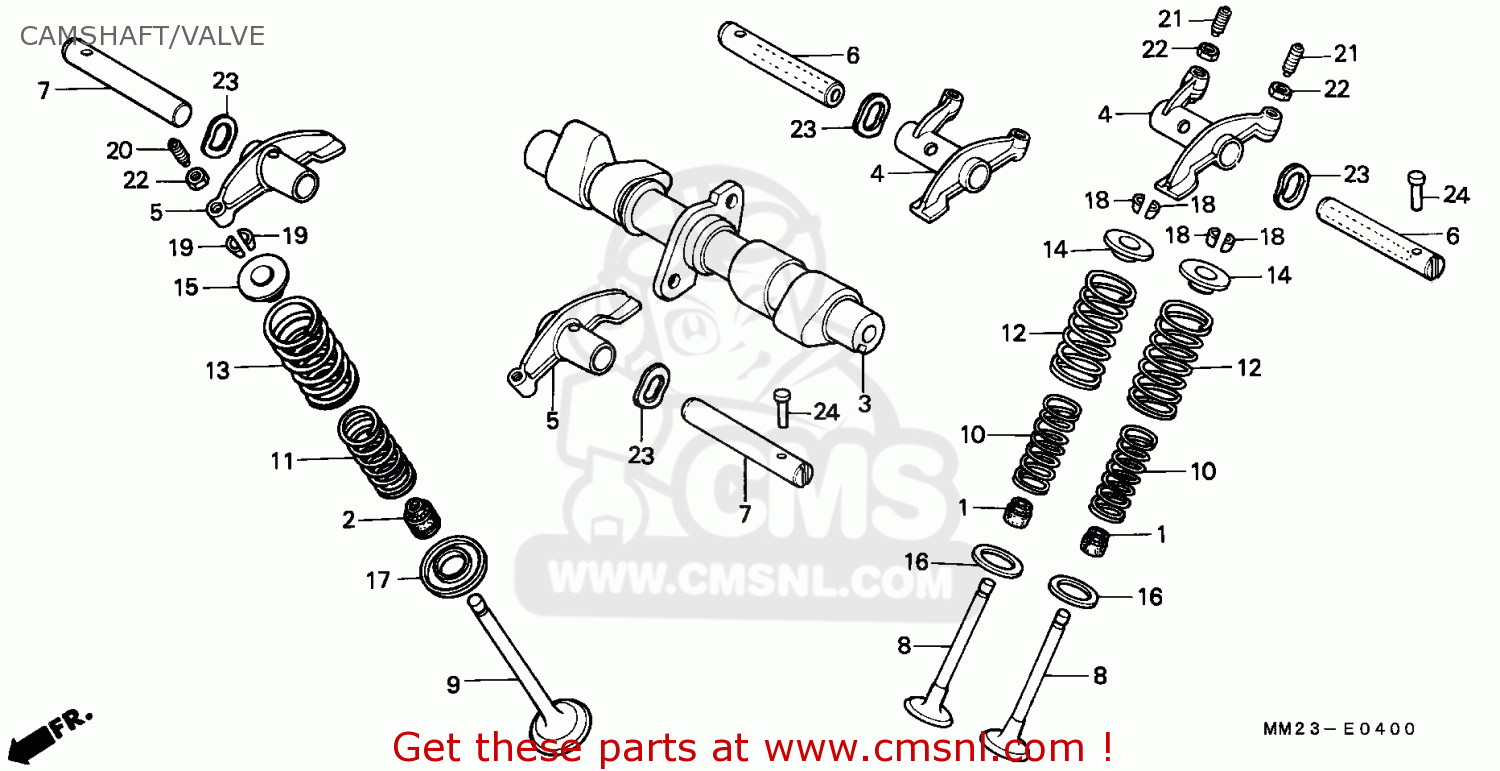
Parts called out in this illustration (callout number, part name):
1	SEAL VALVE,STEM
2	SEAL,VALVE,STEM
3	CAMSHAFT
4	ARM IN ROCKER
5	ARM EX ROCKER
6	SHAFT,IN ROCKER A
7	SHAFT,EX ROCKER A
8	VALVE,IN.
9	VALVE,EXHAUST
10	SPRING,IN.VALVE I
11	SPRING,EX.VALVE I
12	SPG,IN VALVE OUT.
13	SPRING,EX.VALVE O
14	RETAINER
15	RETAINER,VLV.SPG.
16	SEAT,OUTER
17	SEAT,VALVE SPRING
18	COTTER,VALVE
19	COTTER,VALVE
20	SCR,TAPPET ADJG.
21	SCREW,TAPPET ADJ
22	NUT, TAPPET ADJG.
23	WASHER,WAVE,12MM
24	PIN,ROCKER SHAFT
